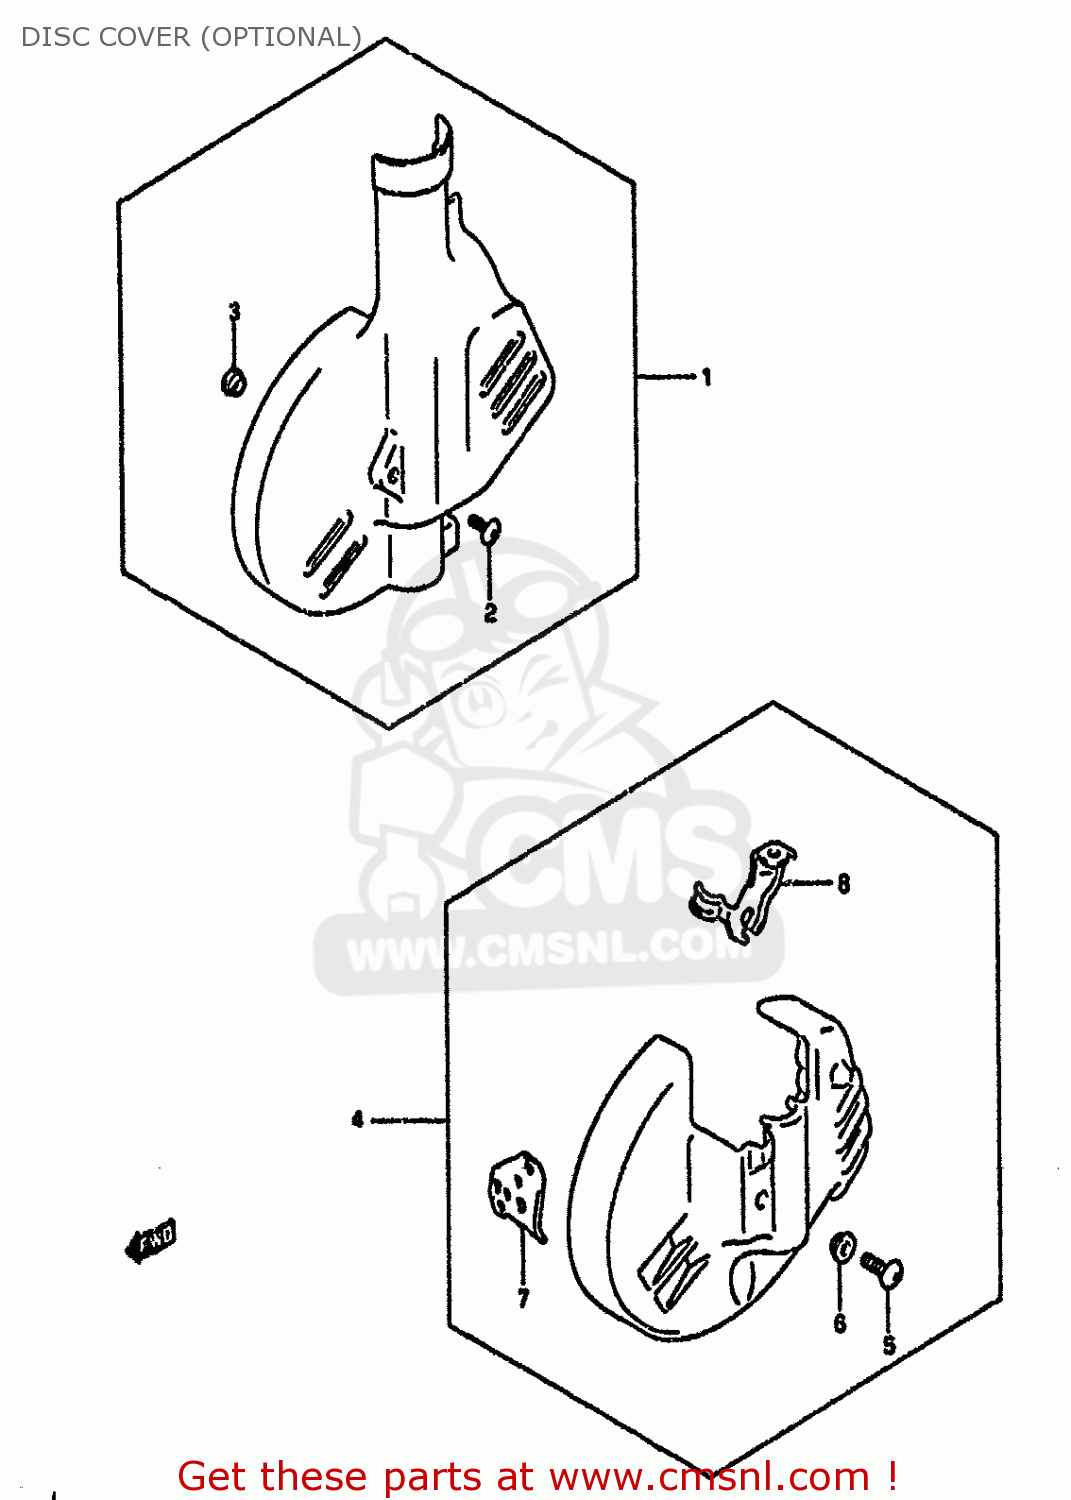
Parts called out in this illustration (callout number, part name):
1	COVER SET,FRONT DISC
2	SCREW(8X12)
3	WASHER
4	COVER SET,FRONT DISC
5	SCREW 6X12
6	WASHER
7	CLAMP,FRONT BRAKE HOSE
8	CLAMP,FRONT BRAKE HOSE
